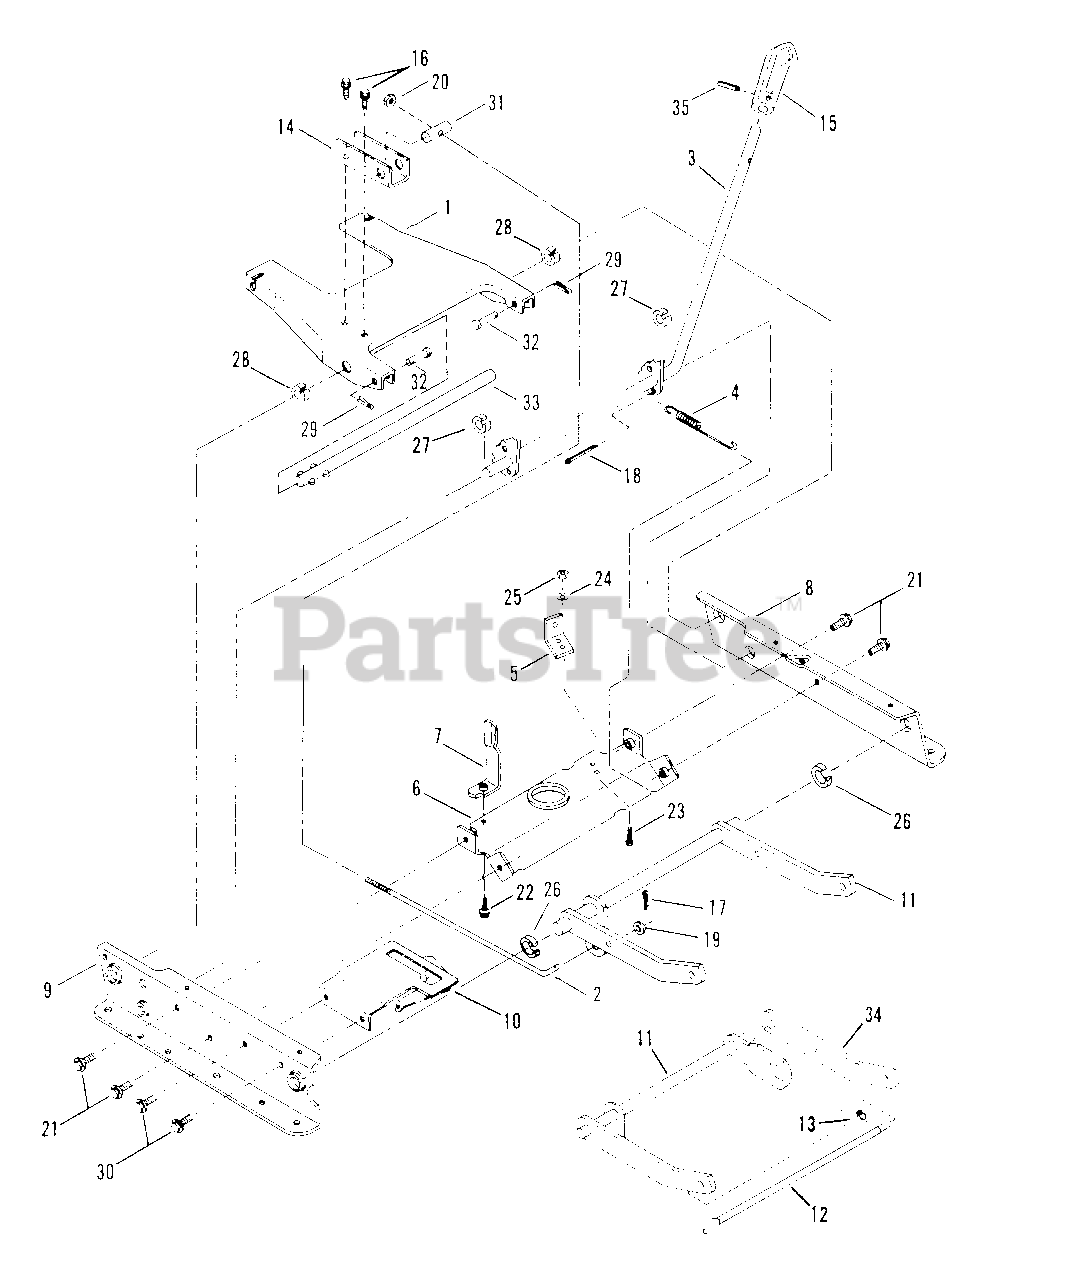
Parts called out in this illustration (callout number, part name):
1	ARM, Rear Lift
2	ROD, Leveling (15.3" L, 3/4-24 thread)
3	WELDMENT, Lift Lever
4	SPRING, Cam Lever
5	ANCHOR
6	BRACE, Top
7	GUIDE, Belt
8	RAIL, Left Hand
9	RAIL, Right Hand
10	ASSEMBLY, Clutch Plate
11	ARM, Front Lift, Non-Adjustable
11	ARM, Front Lift, Adjustable
12	ROD, Support (Front Lift Arm to Front End)
13	RING, 7/16 Retaining
14	ARM, Leveling
15	GRIP, Height Adjustment Lever
16	SCREW, 3/8-16 x 1/2" Self-Tapping
17	PIN, 1/8 x 3/4" Cotter
18	PIN, 5/32 x 1" Cotter
19	WASHER, 3/8" Flat
20	NUT, 3/8-24 Hex
21	SCREW, 3/8-16 x 1/2" Self-Tapping
22	SCREW, 5/16-18 x 5/8" Self-Tapping
23	SCREW, 5/16-24 x 3/4" Hex Head Cap
24	WASHER, 5/16 Internal Tooth Lock
25	NUT, 5/16-24 Hex
26	RING, Red
27	RING, White
28	RING, White
29	PIN, 3/32 x 3/4" Cotter
30	SCREW, 5/16-18 x 1/2" Self-Tapping
31	PIVOT, Leveling
32	PIN, 3/8 x 1 1/16" Clevis
33	SHAFT, Pivot
34	ARM, Front Lift-Left
35	PIN, 3/16 x 3/4" Roll
